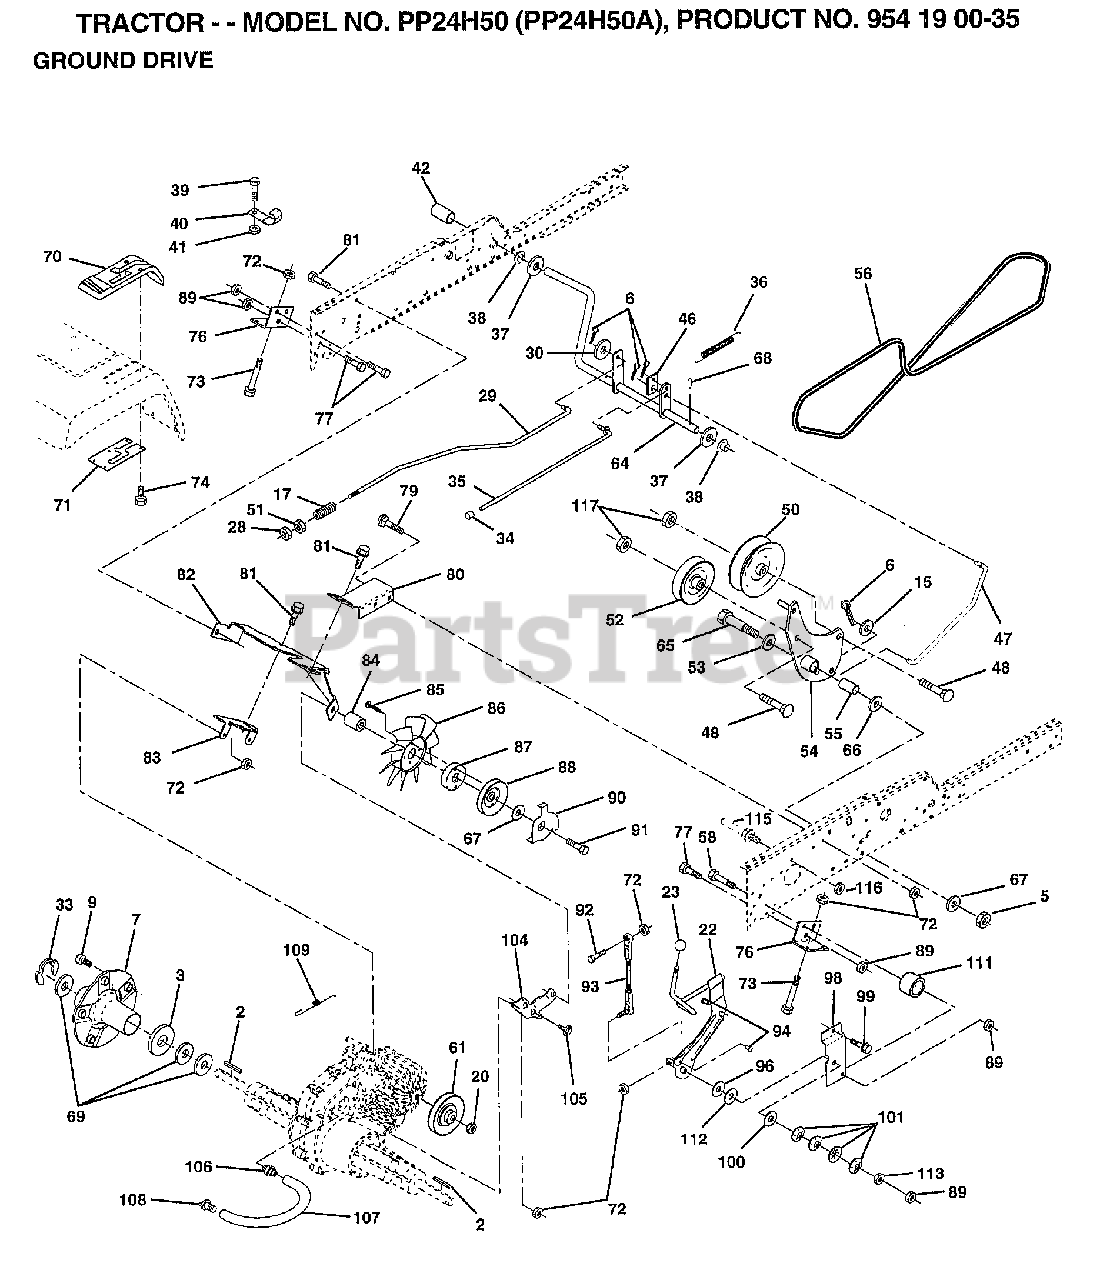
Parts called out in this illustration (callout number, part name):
2	KEY 1/4 X 2.5
3	WASHER T
6	COTTER PIN
7	HUB WHEEL ASM
9	BOLT.HUB.WHL.REAR
15	WASHER
17	SPRING ROD BRAKE
22	ARM ASM SHIFT
23	KNOB.DUCKHEAD.1/2
28	NUT
29	ROD BRAKE
30	WASHER HYT
33	E RING HYT
34	PLUNGER CAP T
35	ROD BRAKE PART GT
36	SPRING.GRND.DRIVE
37	WASHER
38	BUSHING.NYLINER
39	SCREW
40	ACT-SWITCH T
42	"COVER,PEDAL"
46	RETAINER.SPRING
47	ROD.CLUTCH
48	BOLT.3/8-16X1.50
50	FLAT IDLER PULLEY
52	PULLEY.IDLER.V.GR
53	WASHER T
54	CLUTCH.ARM.ASM
55	"LY, BEARING"
56	BELT-V 84.5
58	BOLT
61	PULLEY TRANSAXLE
64	SHAFT-BRAKE/CLUTC
65	AXLE BOLT
66	WASHER.HARD.BLADE
67	WASHER
68	ROLL PIN STD
69	WASHER
70	CONSOLE.SHIFT.AUTO.YT/GT.BLACK
71	"PLATE CONSOLE,SFT"
72	NUT
73	BOLT.HEX.FLGHD.
74	SCREW HEXWSH H-L
76	BRACKET TRAN VGTH
77	BOLT
79	BOLT
80	BRACKET TORQUE RH
81	SCREW
82	BRACKET.MTG.FAN
83	STRAP TORQUE MID
84	SPACER
85	SCREW YTV
86	"FAN 7"" HYDRO"
87	ADAPTER FAN
88	PULLEY FAN
89	NUT GTV
90	KEEPER BELT
91	SCREW.HXWSH.3/8
93	LINK ASM SHIFT
94	XMAS TREE FASTNER
96	WASHER NICKEL PLT
98	BRACKET SHIFT
99	SCREW LT
100	WASHER COMPRESSIN
101	WASHER-BELLVILLE
104	BRACKET IDLER
105	SCREW CRT
106	O-RING.ASM.70110
107	"LINE FUEL,HYD 15"""
108	CAP.VENT.70109
109	SPRING BRAKE
111	"SPACER-LEVER,SHIF"
112	"WASHER-NYLON,HIGH"
113	NUT
115	"KEEPER,DRIVE BELT"
116	"NUT HEX,LOCK,FLAN"
